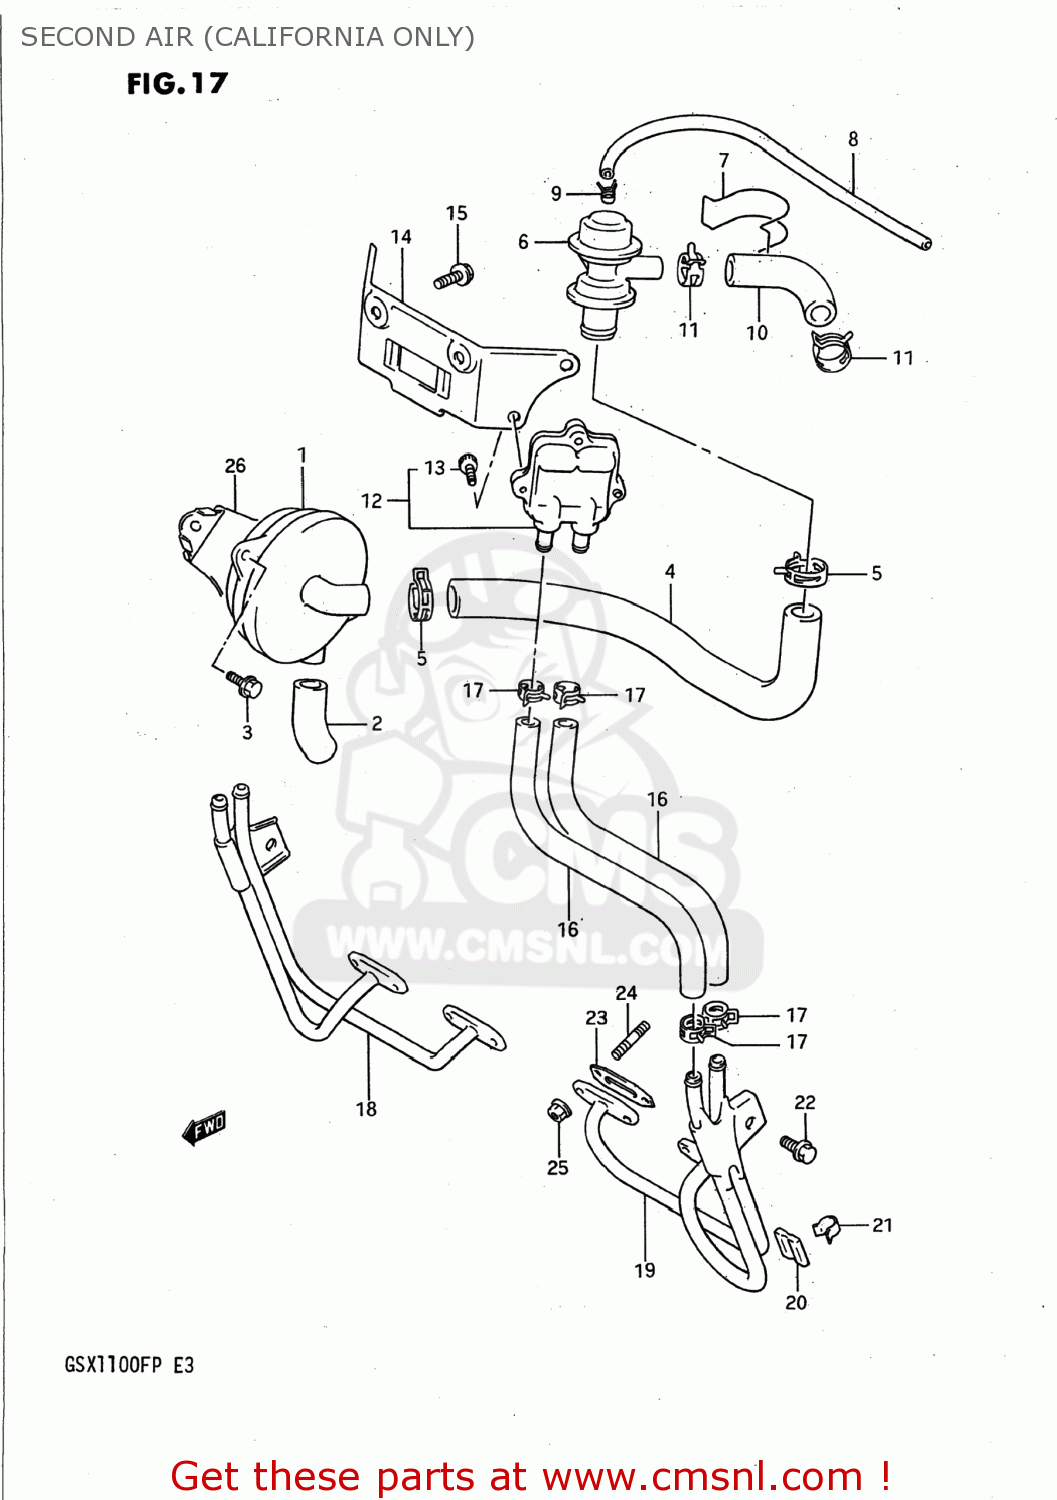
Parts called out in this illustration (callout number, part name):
1	CLEANER ASSEMBLY,SECOND AIR
2	HOSE,SECOND AIR CLEANER
3	BOLT
4	HOSE,SECOND AIR NO.3
5	CLIP
6	VALVE ASSY,AIR SWITCHING
7	CLAMP,SWITCHING VALVE
8	HOSE
9	CLAMP
10	HOSE,SECOND AIR NO.2
11	CLIP
12	VALVE ASSY,2ND AIR REED
13	BOLT
14	(CA) BRACKET,REED VALVE
15	BOLT
16	HOSE,SECOND AIR NO.1
17	CLIP
18	(CA) PIPE ASSEMBLY,SECOND AIR
19	(CA) PIPE ASSEMBLY,SECOND AIR
20	(CA) CUSHION
21	(CA) CLIP,SECOND AIR PIPE
22	BOLT 6X12
23	GASKET,SECOND AIR PIPE (NAS)
24	STUD 6X16
25	NUT 6MM
26	HOLDER,SECOND AIR CLEANER
